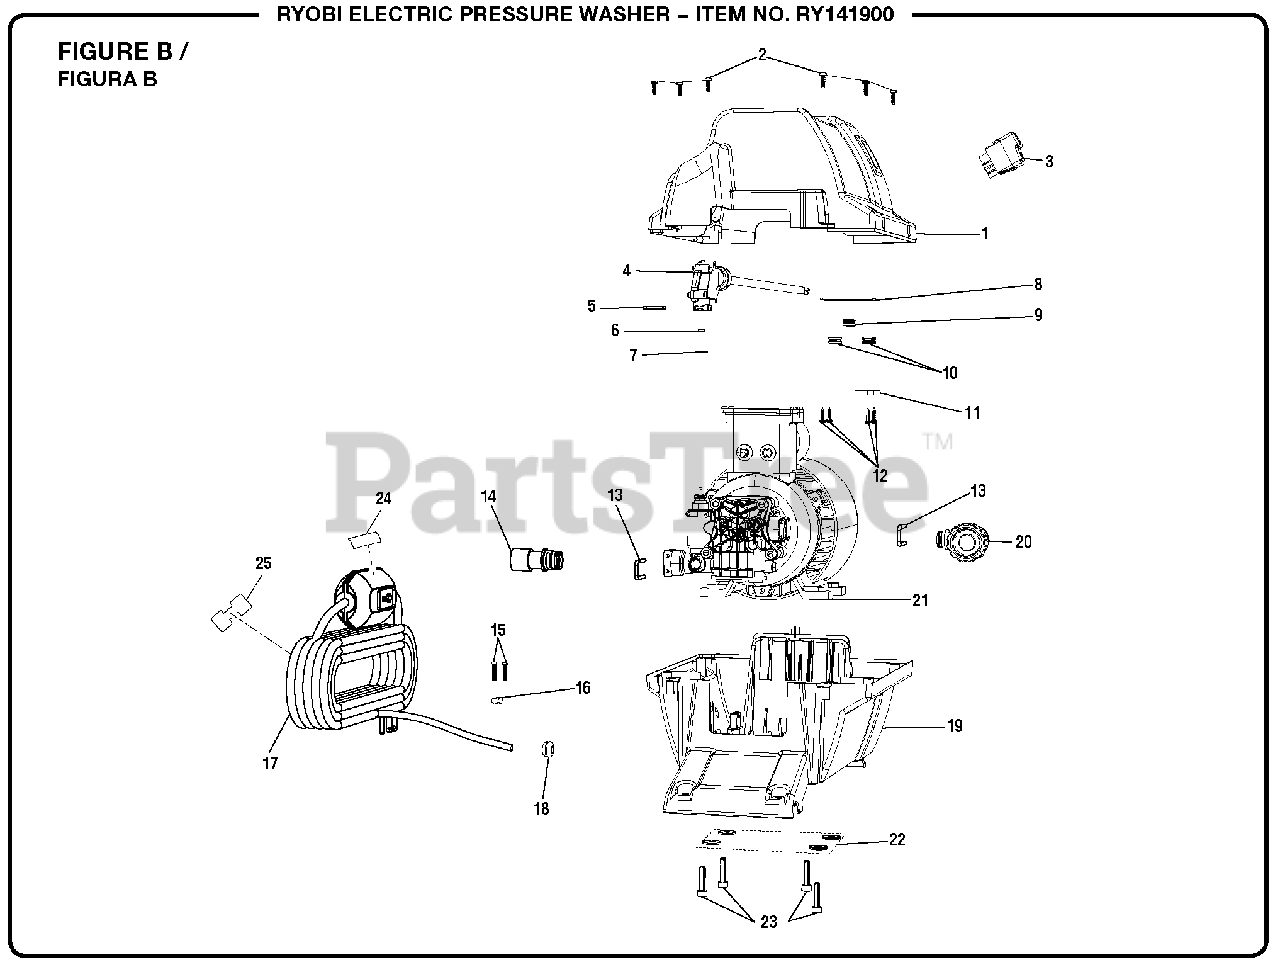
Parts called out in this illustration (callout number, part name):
1	Top Motor Housing
2	Screw (M4 x 15 mm)
4	Pressure Switch
6	O-Ring
7	Brass Washer (OD11.2 x ID3.4 x 1t)
8	Switch Cover Gasket
11	Switch Cover
12	Screw (M3 x 14 mm)
14	Outlet Pump Assembly
15	Screw (M3.5 x 20 mm)
16	Cord Clamp
17	Power Cord
19	Lower Motor Housing
20	90 degree Inlet Assembly
21	Pump Assembly
22	Washer (OD18 x ID6.3 x 1t)
23	Bolt (M8 x 20 mm, Hex Hd.)
24	Cord Plug Label
25	Cord Wrap Label
